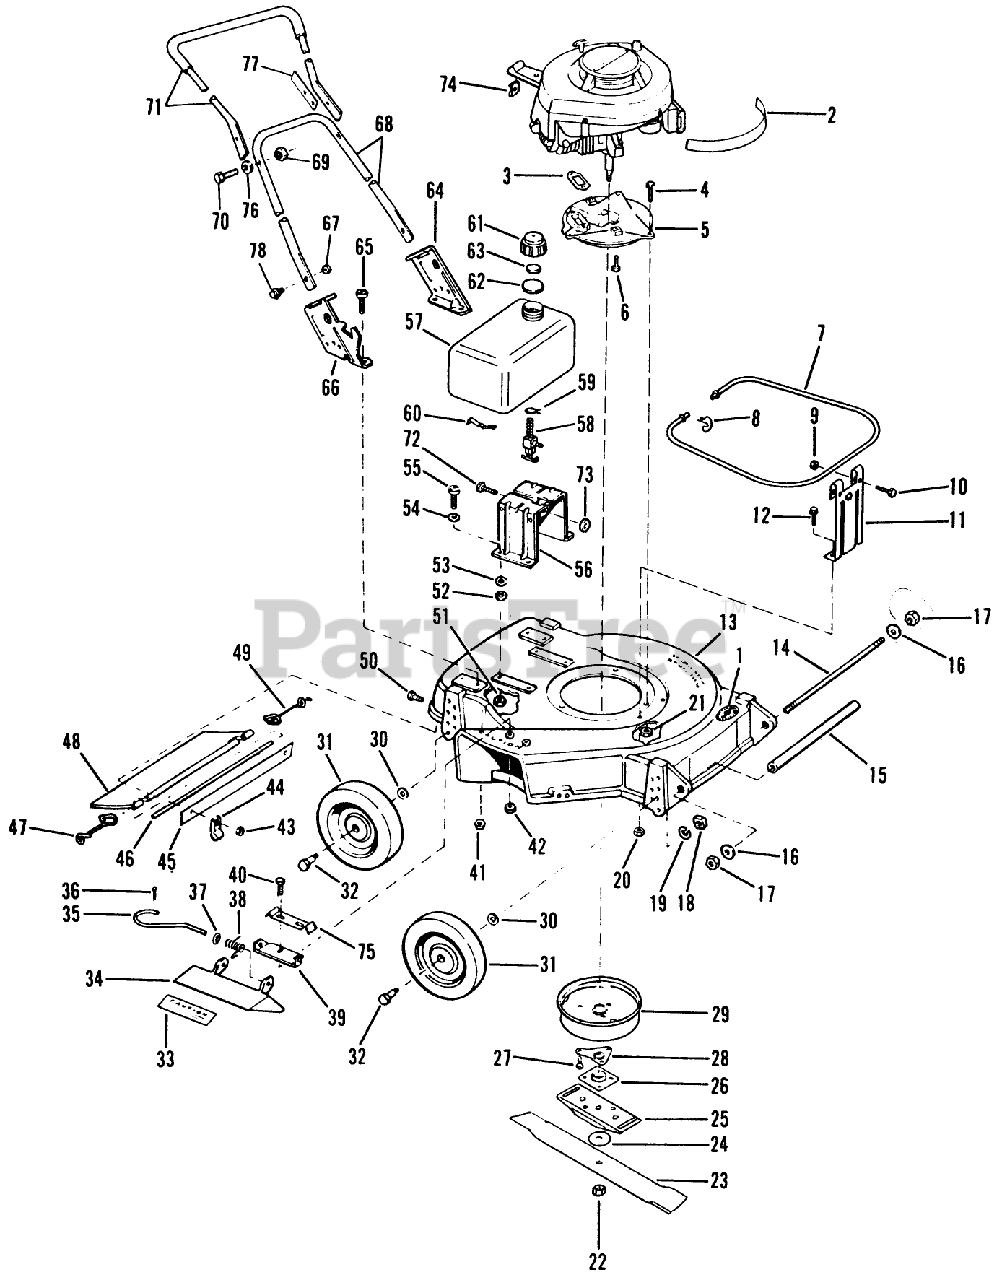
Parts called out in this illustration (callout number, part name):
6	SCREW V
9	LOCKNUT E
16	WASHER WROUGHT
17	LOCKNUT
19	WASHER, LOCK
20	LOCKNUT E
21	NUT-LOCK F
22	NUT-BLADE
26	PLATE AND COLLAR ASM
28	SUPPORT F
30	WASHER WROUGHT
35	HINGE PIN
40	SCREW HEX WASHER
41	LOCKNUT E
42	LOCKNUT E
43	LOCKNUT E
47	SPRING;TRAILING SHIELD RH
49	SPRIG T/SHLD ASOC
51	LOCKNUT E
55	BOLT PIONEER
58	VALVE&SCREEN SM
59	CLAMP - HOSE S
62	GASKET S
63	BAFFLE - FOAM SM
65	SCREW S
67	NUT-JAM, LOCKING
68	Handle Bottom
69	LOCKNUT E
71	Top Handle Grip Assy.
72	SCREW S
74	NUT-SPEED
76	WASHER-CURVED
